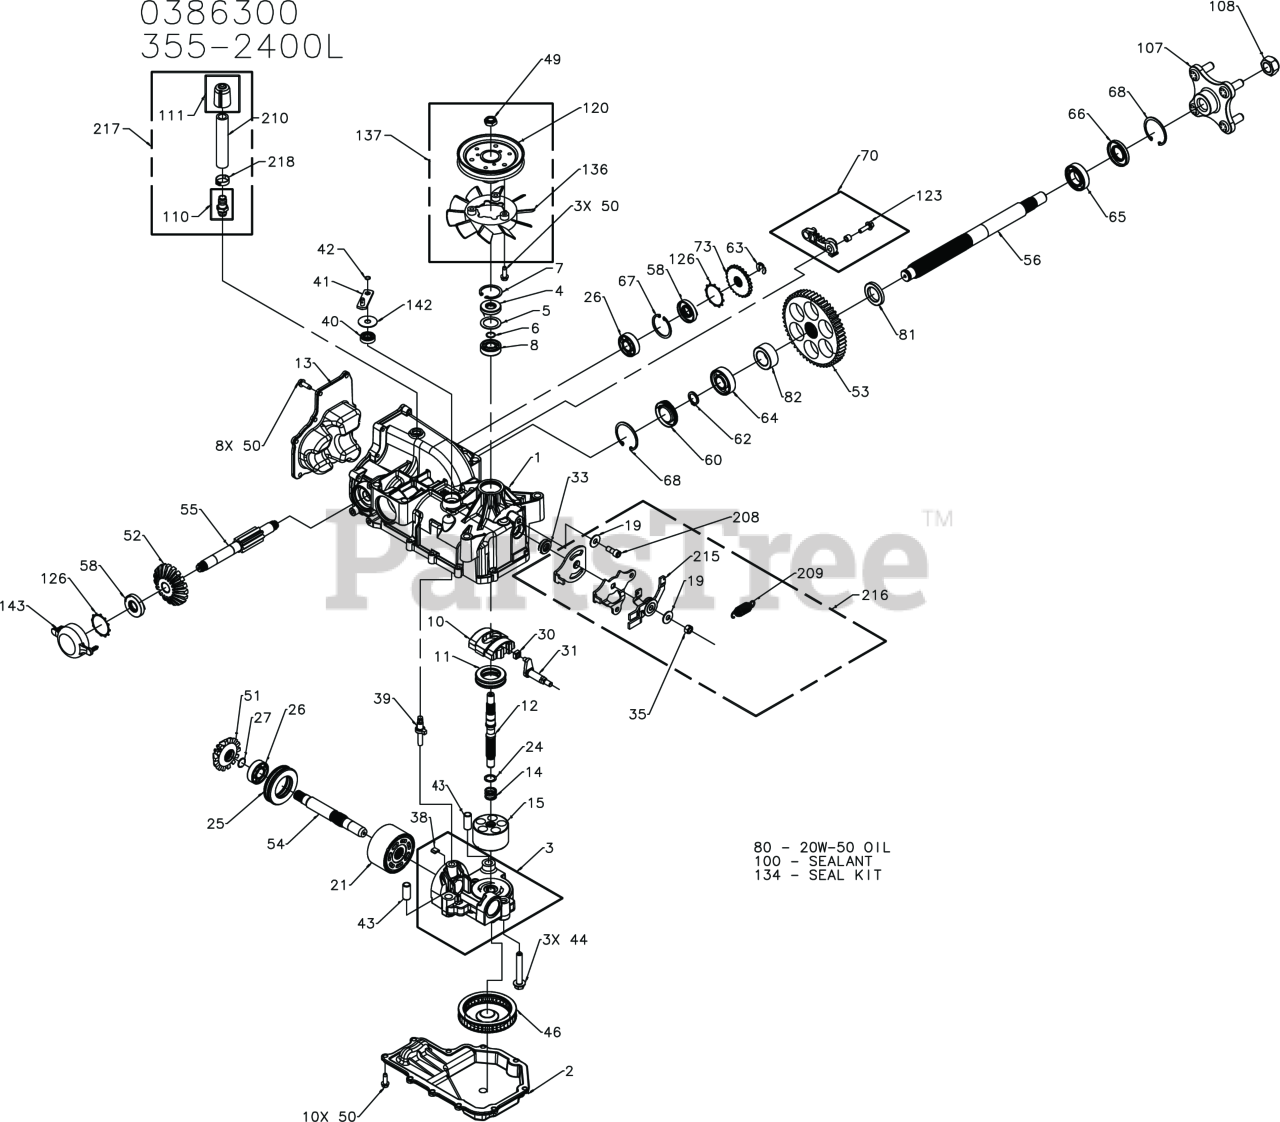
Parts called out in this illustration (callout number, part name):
1	KIT, MAIN HOUSING
2	HSG, IZT LOWER
3	KIT, C-SECTION
4	SEAL, LIP 15X35X7
5	WASHER .98X1.37X.04
6	RING, WIRE RETAINING
7	RING. RETAINING
8	BEARING, SHAFT BALL
10	SWASHPLATE. VARIABLE
11	BEARING. THRUST 30 X 52 X 13
12	SHAFT, INPUT
13	COVER, END IZT
14	SPRING. BLOCK
15	KIT, 10 CC BLOCK
21	ASSEMBLY BLOCK
24	WASHER. THRUST .59 X .79 X .04
25	BRG, THRUST BALL 42X68X16
26	BRG, BALL 17X40X12
27	RING, RET WIRE .561 ID
30	GUIDE. SLOT
31	ARM. TRUNNION TAPERED SQUARE
33	SEAL, LIP 12X25X7
35	NUT, LOCK, 5/16-24 UNF
38	KIT, BYPASS PLATE
39	ACTUATOR, BYPASS
40	SEAL, LIP
41	ARM. BYPASS
42	RING, RETAINING
43	PIN-HOLLOW .39X.5X1.
44	HFHCS 3/8-24X2.5 (PATCH)
49	HEX LOCK NUT, 1/2-20 (NYLON INSERT)
50	HFHCS 1/4-20X.75
51	GEAR, BEVEL 14T
52	GEAR, BEVEL 19T
53	GEAR, SPUR 53T
54	SHAFT, MOTOR
55	SHAFT, BRAKE
56	AXLE, 1.0X12.3
58	SEAL, LIP 17X40X7
60	PLUG, SEAL 1.86
62	RING, RET .75 EXT
63	RING, RET .440 EXT
64	BRG, BALL 20X47X14
65	BRG, BALL 25X47X12
66	SEAL, LIP 25X47X7
67	RING, RET 1.56 INT
68	RING, RET 1.87 INT
70	BRAKE ARM, LH IZT
73	BRAKE, PARK SPLINE
80	FLUID, HYDRO 20W50 QT
80	FLUID, HYDRO 15W50 QT
100	SEALANT TUBE 10.1OZ.
107	ASSEMBLY, HUB
110	FTG-STR .50 O-RING
111	BREATHER ASSEMBLY
120	PULLEY, 4.5 IN
123	SCREW, HFH 1/4-28 X 7/8 PATCH
126	RING, RET 1.43"
134	KIT, SEAL
136	FAN-6IN
137	KIT, FAN/PULLEY
142	WASHER, .392 X 1.250 X .0
143	CAP, BRAKE
208	SHCS 5/16-24X.75
209	SPRING, EXTENSION
210	HOSE .5X4
216	KIT, RTN
217	KIT, BREATHER
